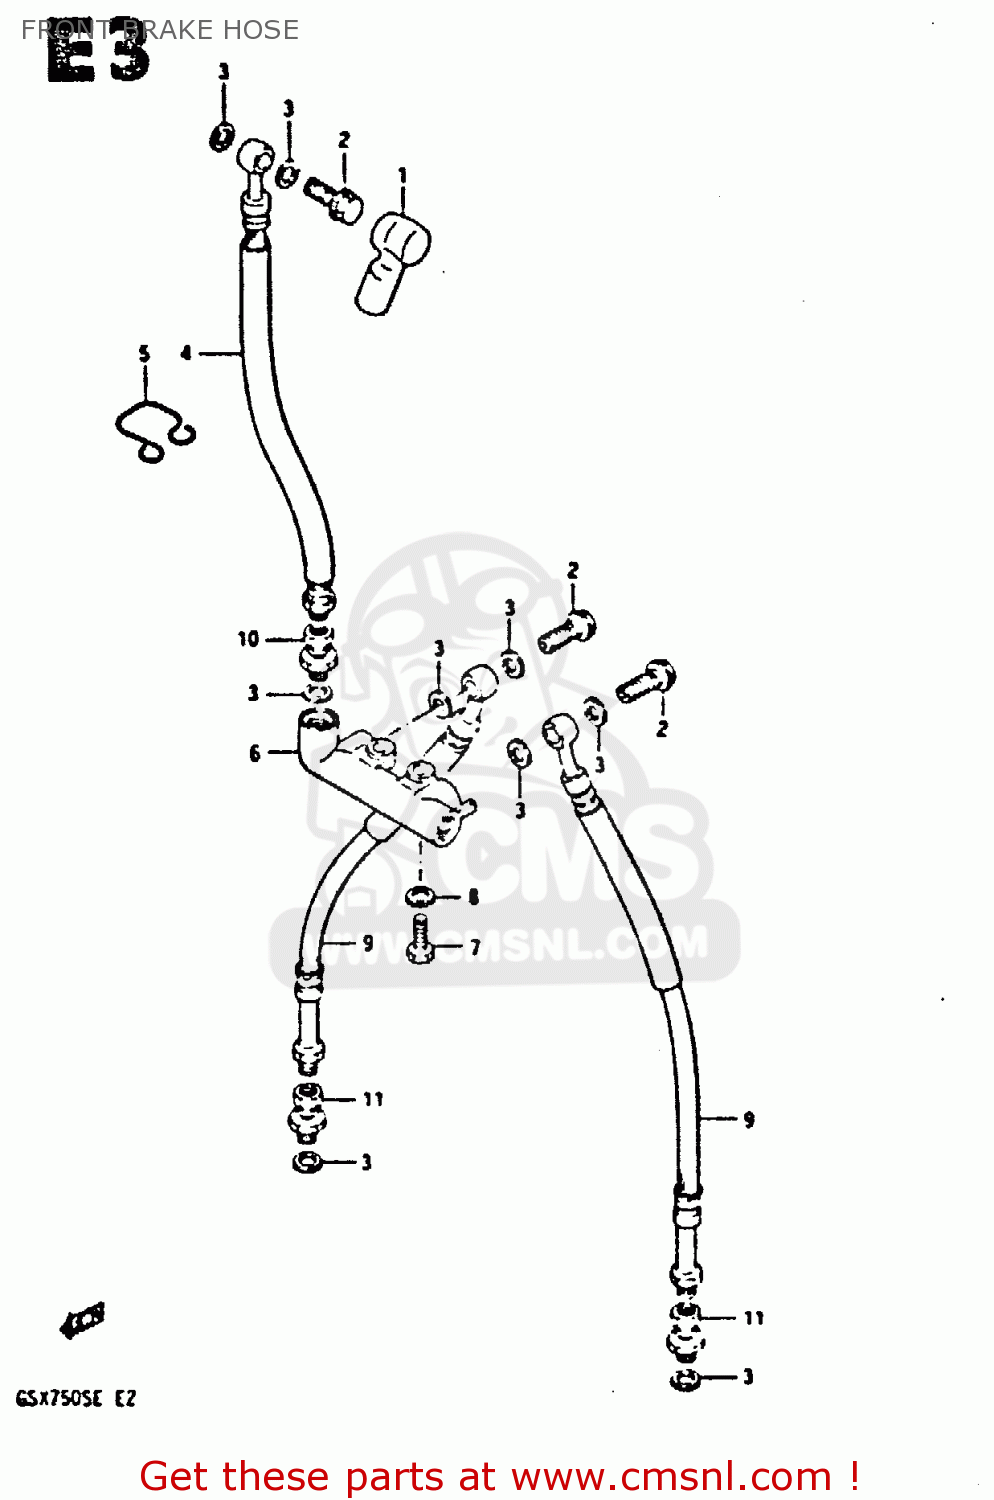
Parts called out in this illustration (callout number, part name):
1	BOOT,MASTER CYLINDER
2	BOLT UNION
3	WASHER(10X15X1.5)
4	HOSE, FRONT BRAKE NO.1
5	GUIDE,CABLE/HARNESS
6	JOINT
7	BOLT
8	WASHER,LOCK
9	HOSE, NO.2
10	ADAPTER,BRAKE HOSE
11	ADAPTOR
